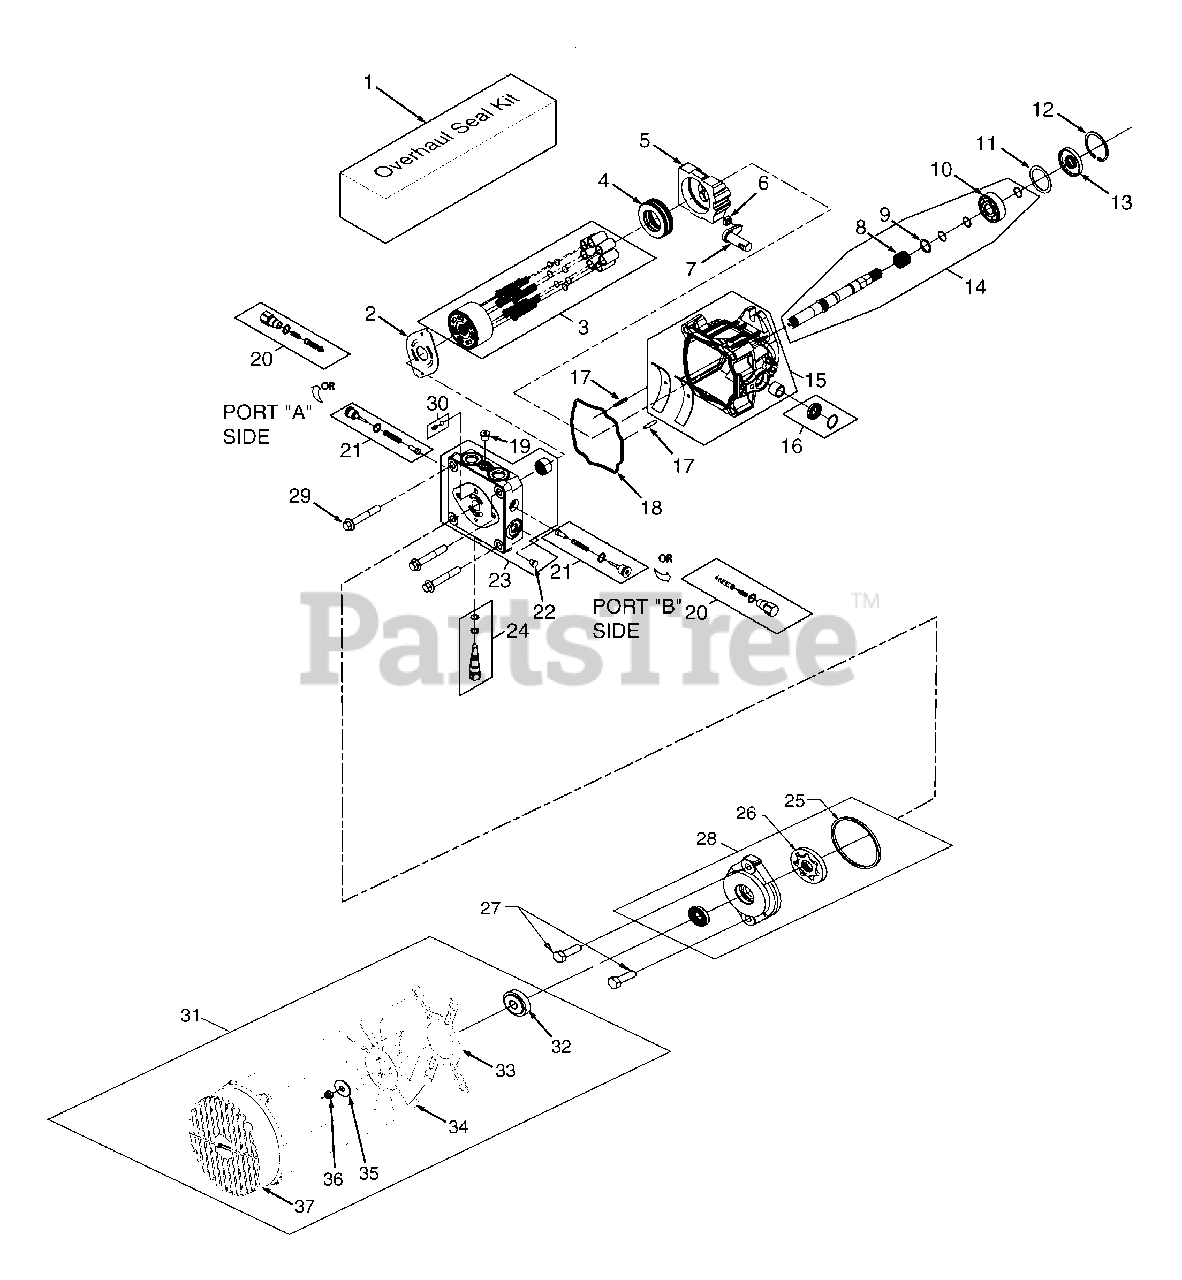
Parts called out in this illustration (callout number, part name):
1	Overhaul Seal Kit
2	Valve Plate
3	Cylinder Block Kit - 16cc
4	Thrust Ball Bearing Assembly
5	Variable Swashplate
6	Slot Guide
7	Trunnion Arm
8	Block Spring
9	Block Thrust Washer
10	Shaft Ball Bearing
12	Retaining Ring
14	Kit, Pump Shaft (keyed thru taper)
15	Housing Kit
16	Trunnion Seal Kit
18	O-Ring
19	Straight Thread Plug
20	Shock Valve Kit (.031 Orifice)
21	Shock Valve Kit (.024 Orifice)
22	Straight Thread Plug
23	End Cap Kit
24	Bypass Valve Kit
26	Gerotor Assembly (.19 cu.in./rev.)
27	Socket Head Cap Screw (M8 x 1.25-25mm)
28	Charge Pump Kit (.19 STD. Splined)
29	Hex Screw, Flanged Head (M10 x 1.50-65mm)
30	Charge Relief Kit
31	Fan Kit
33	Bracket, Shroud
35	Washer
37	Shroud
